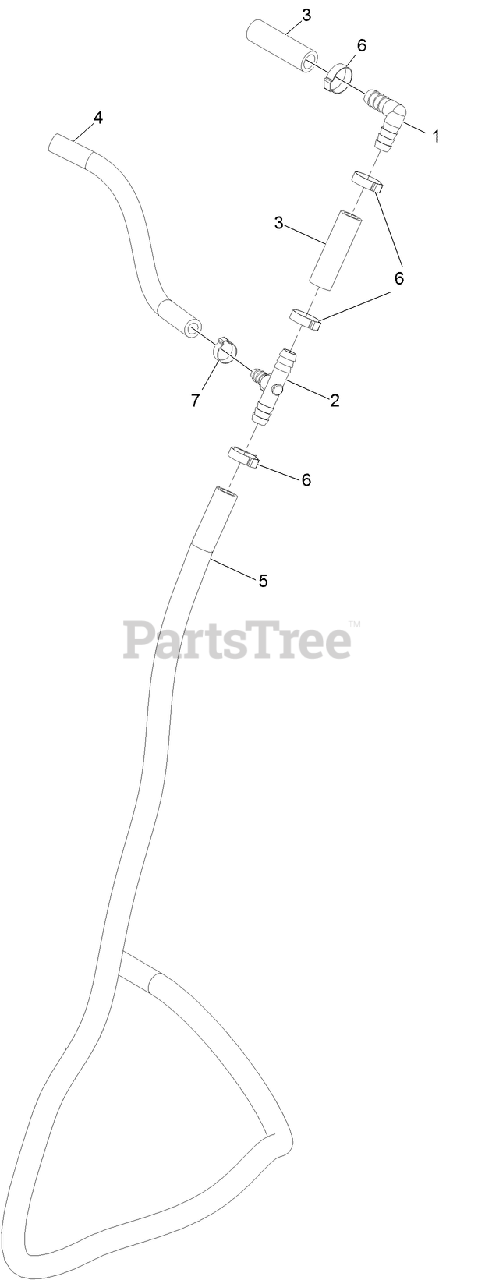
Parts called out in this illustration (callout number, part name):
1	FITTING-ELBOW-90
2	CONNECTOR-TEE
3	HOSE-WATER
4	HOSE-WATER
5	HOSE-WATER
